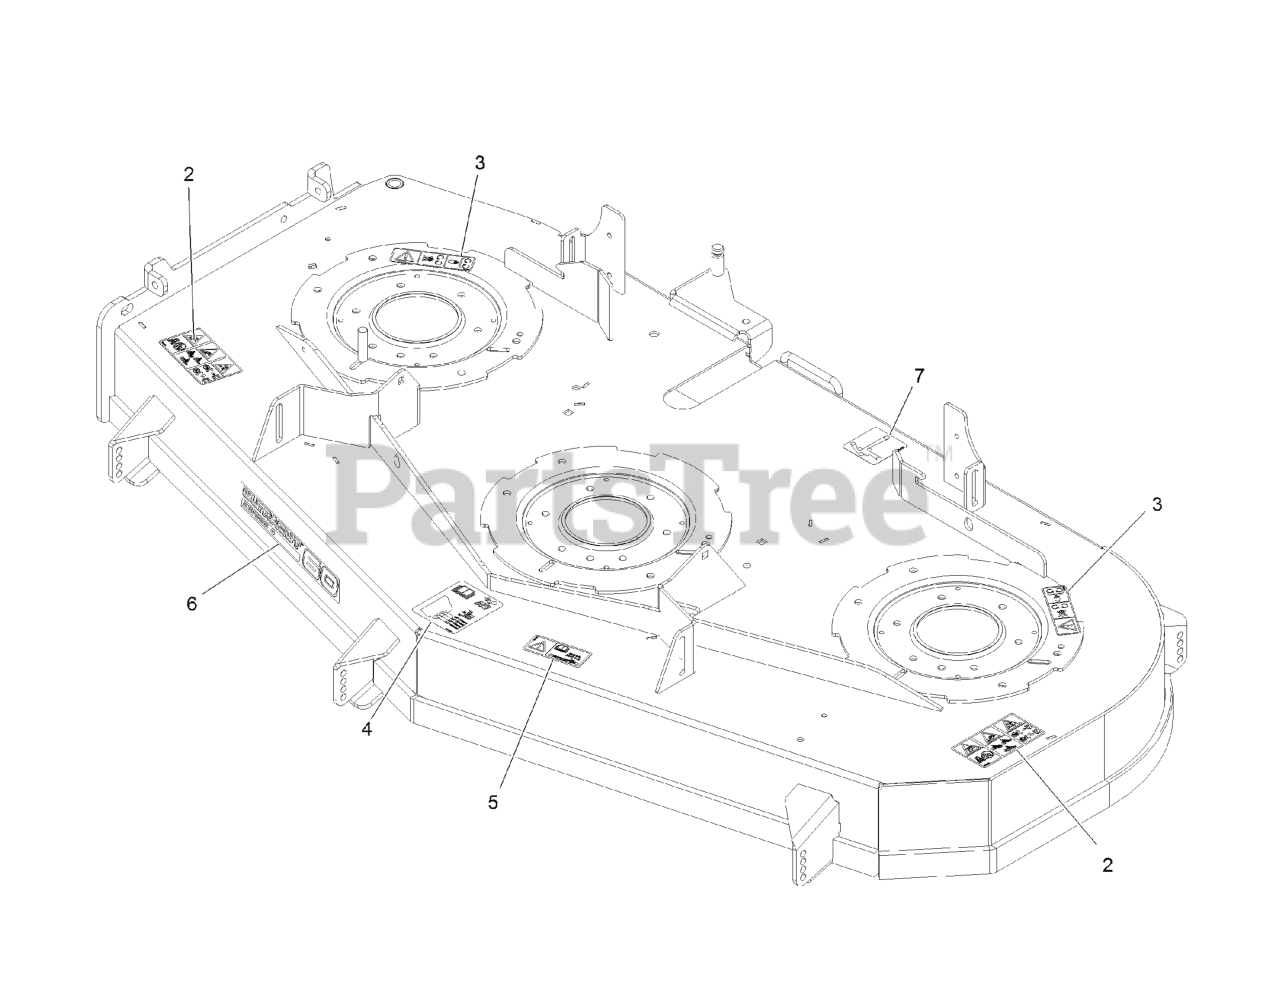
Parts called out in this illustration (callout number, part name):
2	DECAL-DANGER THROWN OBJECTS
3	DECAL-COVER, MISSING
4	DECAL-ROLLER, ANTI-SCALP
5	DECAL-BOLT TORQUE
6	DECAL, 604
7	DECAL-ROUTING, BELT
